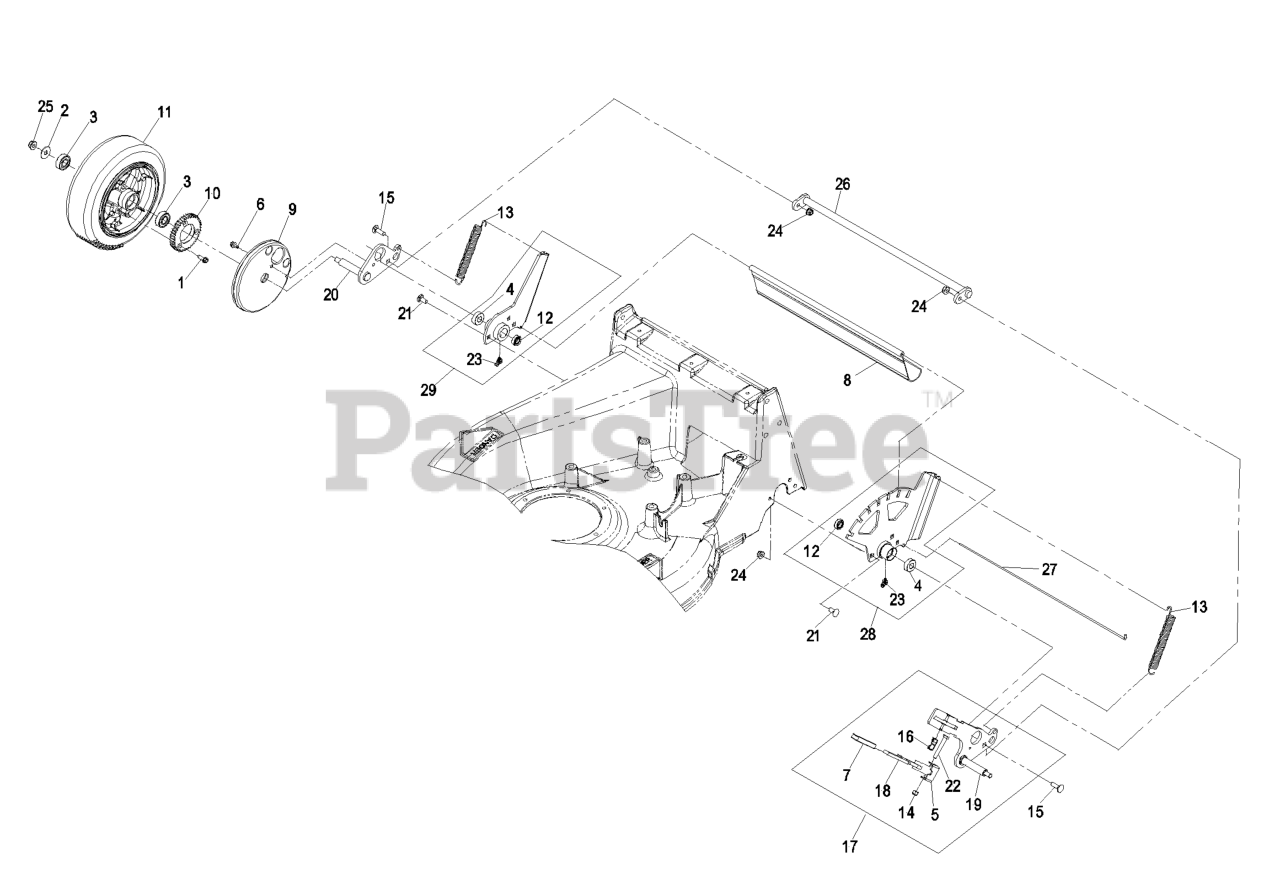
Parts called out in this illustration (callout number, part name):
3	BEARING-BALL
4	BEARING-AXLE, REAR
5	BRACKET-PIVOT, LIFT
7	COVER-HANDLE
9	COVER-GEAR
10	GEAR-DRIVEN
11	ASM,10" TIRE AND WHEEL
12	SEAL-AXLE
13	SPRING-ASSIST, LIFT
14	NUT-LOCK, NI
15	BOLT-CARR
16	SPRING-LATCH
17	ASM,REAR ADJUSTER
18	LEVER-LIFT
19	ARM-AXLE, LH
20	ARM-AXLE, RH
21	BOLT-CARR
22	SCREW-HH
23	FITTING-GREASE
24	NUT-HF, NI
25	NUT-HF, NI
26	ROD-TORQUE
27	ROD-SHIELD
28	LH BEARING SUPPORT ASM
29	RH BEARING SUPPORT ASM
